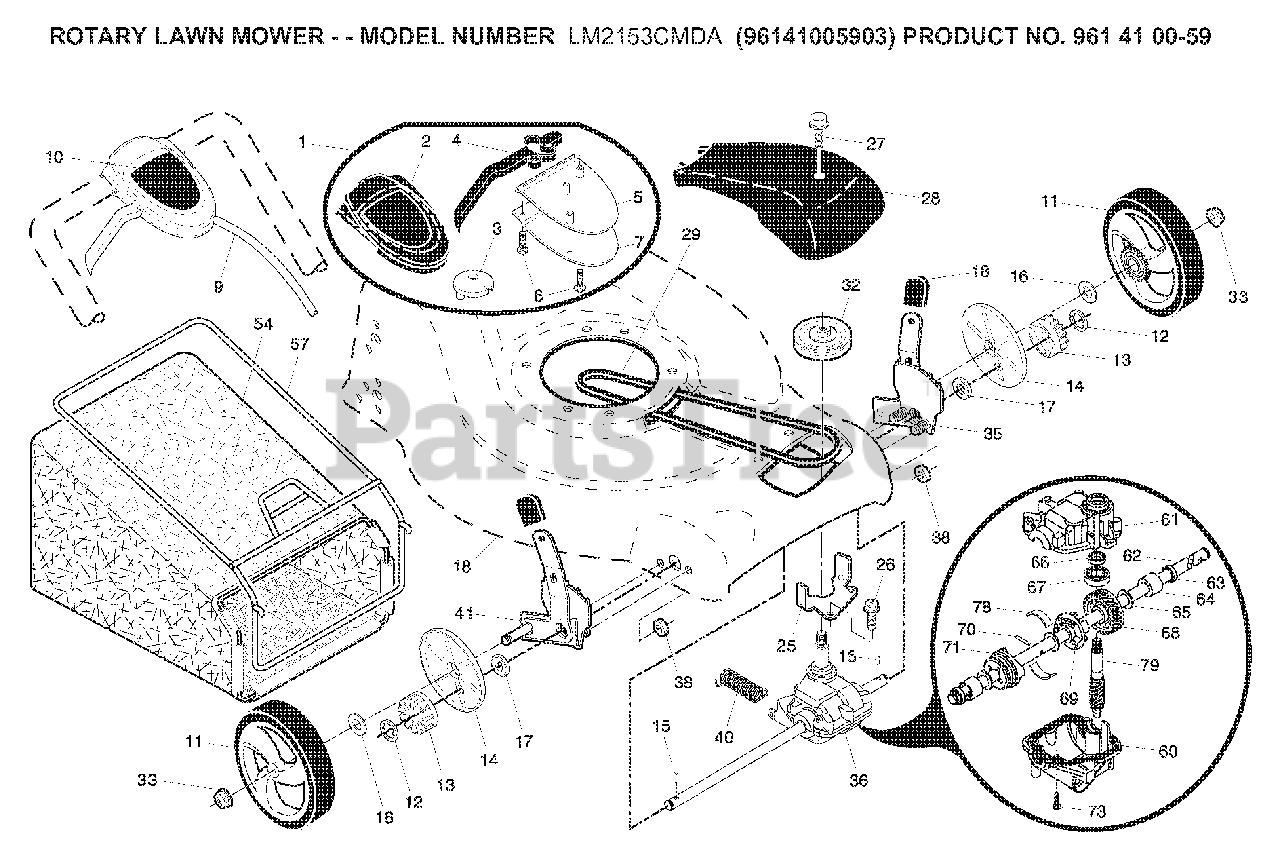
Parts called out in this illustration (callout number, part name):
1	CONTROL.DR.EZ.FGD.SHORT.BK/RED
2	COVER, TOP DRIVE CONTROL
3	PULLEY.CAM.DRIVE.CONTROL.EZ
5	COVER BOTTOM DRIVE CNTRL BLACK
6	SCREW, PHILLIPS HEAD 10 X 5/8
7	BRACKET.DRIVE.CONTROL.MOUNT
9	CABLE ASSEMBLY, DRIVE
12	E-RING 7/16 RE
13	PINION.14.TEETH.FGD
14	COVER.DUST.WHEEL
15	PAWL, DRIVE
16	WASHER FLUT
17	BEARING
18	SELECTOR KNOB
25	BELT KEEPER
27	SCREW, HEX HD TAPPING #10-24 1
29	BELT.DRIVE.FG
32	RP PULLEY.DRIVE.EZ
33	NUT.HEX.FLANGE.3/8-16.LOCKNUT
35	WHEEL ADJ KIT LH
36	TRANSMISSION.21.FGD.HT.VST
38	LOCKNUT
41	WHEEL ADJ KIT RH
54	GBAG.34710010.BLACK.GE
57	FRAME.GBAG.21.FWGD
60	CASE.BOTTOM.
61	CASE.UPPER.00254(SERVICE)
62	SHAFT OUTPUT
63	SEAL.OUTPUT.SHAFT
66	SEAL INPUT SHAFT
68	GEAR 28 TEETH
69	FIXED DOG CLUTCH
70	PIN.3.50.33733
71	MOVEABLE DOG CLUTCH
78	SPRING LEAF
79	SHAFT WORM
